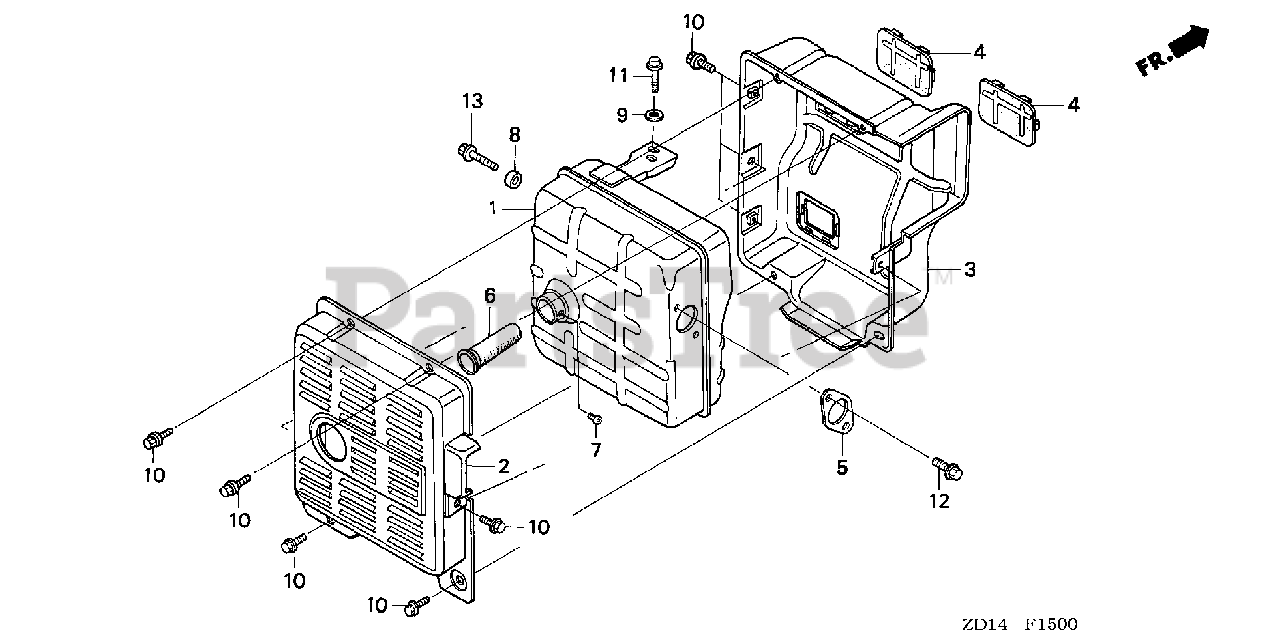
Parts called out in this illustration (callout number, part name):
1	MUFFLER (SANKEI)
2	PROTECTOR, MUFFLER (OUTER)
3	PROTECTOR, MUFFLER (INNER)
4	SEAL, MUFFLER PROTECTOR
5	GASKET, EX. PIPE
6	ARRESTER, SPARK
7	SCREW, TAPPING (4X8)
9	WASHER, PLAIN (8MM)
10	BOLT, FLANGE (6X10)
11	BOLT, FLANGE (8X16)
12	BOLT, FLANGE (8X20)
13	BOLT, FLANGE (8X25)
